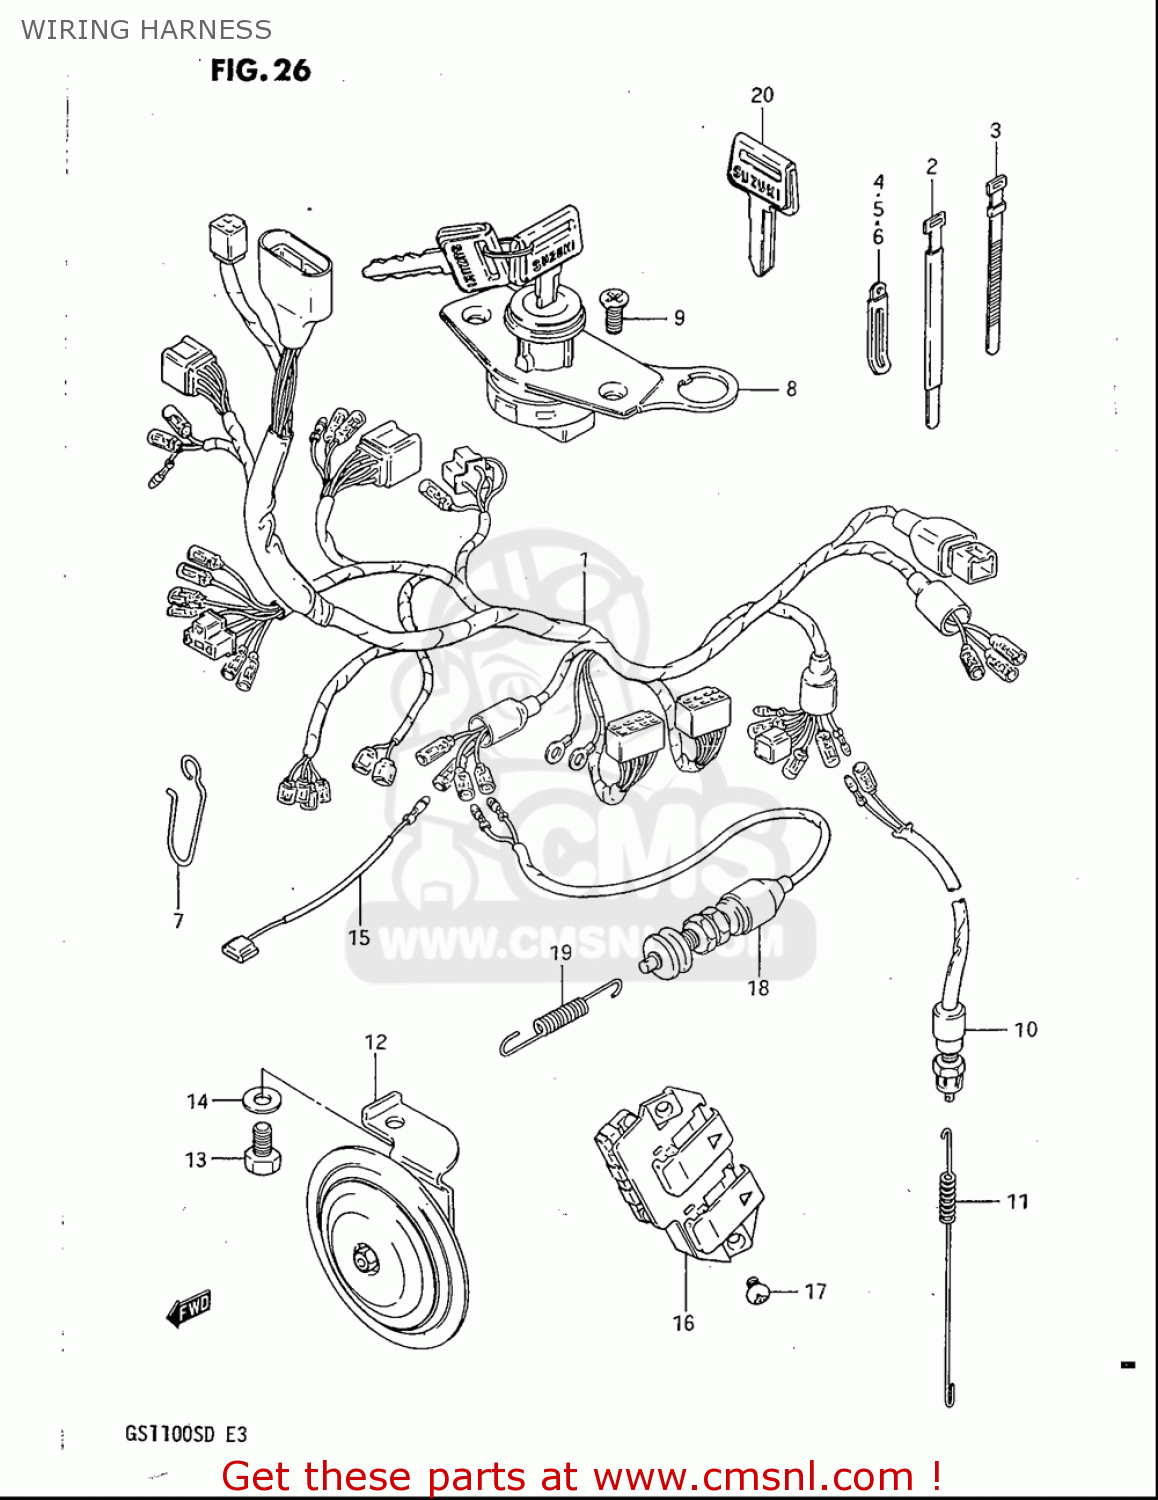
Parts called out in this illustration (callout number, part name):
2	CLAMP
3	CLAMP(L:120)
4	CLAMP(L:65)
5	CLAMP(L:80 T:1.0)
6	CLAMP(L:65)
7	GUIDE,WIRING HARNESS
9	SCREW
10	SWITCH ASSY,STOP LAMP
11	SPRING
12	HORN ASSY
13	BOLT
14	WASHER
15	WIRE,OIL PRESSURE SWITCH LEAD
16	SWITCH ASSY,SIDE COVER,L
17	SCREW
19	SPRING
20	KEY,BLANK
